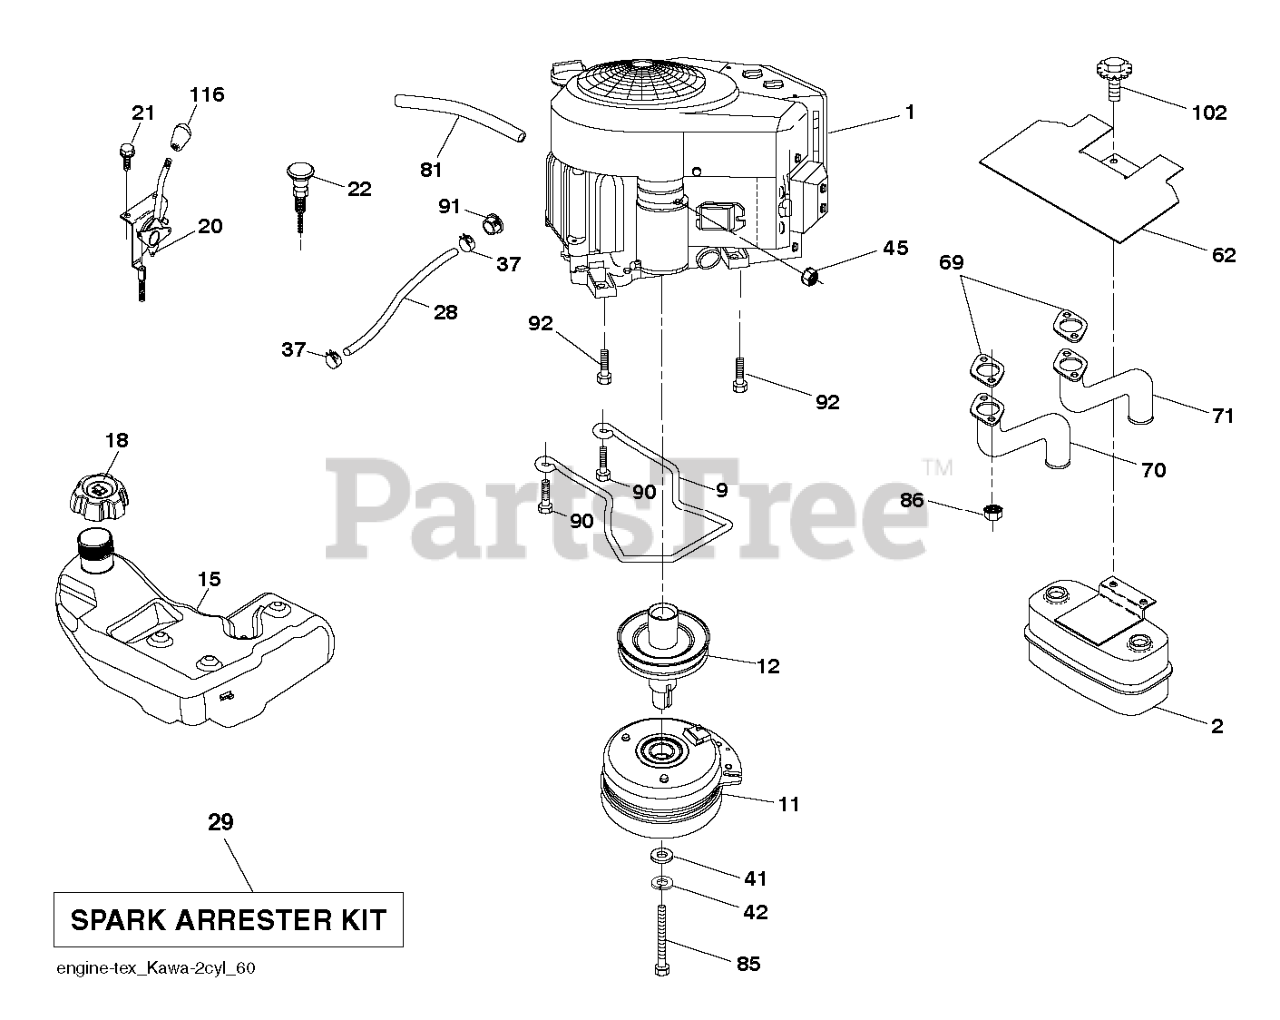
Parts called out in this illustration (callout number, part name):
2	MUFFLER.ASM.TWIN.MNTG.BRACKET
9	KEEPER.BELT.ENG.4.25"2.BLT.431
11	CLUTCH. 5.0 PD. 2.5 OFFSET
12	PULLEY.EXTENDED.SHAFT.GROUND
15	TANK.ASM.3GAL.EPA.17
18	CAP ASSY FUEL 3" GRAY
20	CONTROL.THROTTLE.PRO.
21	SCREW.#10 X 0.750.BOS
22	CONTROL, CHOKE
28	LINE.FUEL.64"REAR.EMIS
29	KIT.SPARK ARRESTOR 794945 B&S
37	HOSE CLAMP
42	LOCKWASHER
45	NUT
62	SHIELD.HEAT.MUFFLER
70	TUBE.EXHAUST.LH.FR961/FR730
71	TUBE.EXHAUST.RH.FR961/FR730
81	TUBE, DRAIN OIL ASM.
85	BOLT.HEX.7/16-20 X 5
86	NUT.HEX.FLANGE.TOPLOCK
90	SCREW 3/8-16X1
91	BUSHING.1.375OD
92	SCREW 3/8-16X1
102	SCREW
116	KNOB - SHIFT
